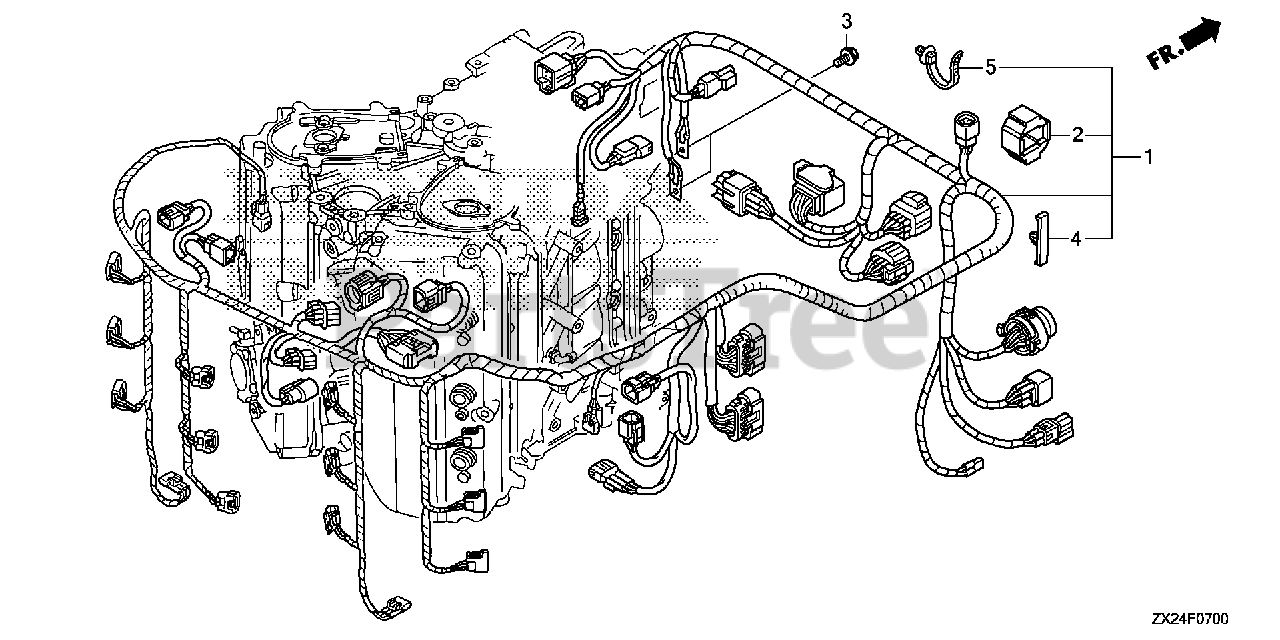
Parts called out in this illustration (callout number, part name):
1	WIRE HARNESS ASSY., MAIN
2	SUSPENSION, CONNECTOR
3	BOLT, FLANGE (6X12)
4	CLIP, WIRE HARNESS
5	CLIP, HARNESS BAND (145MM) (BLACK)
